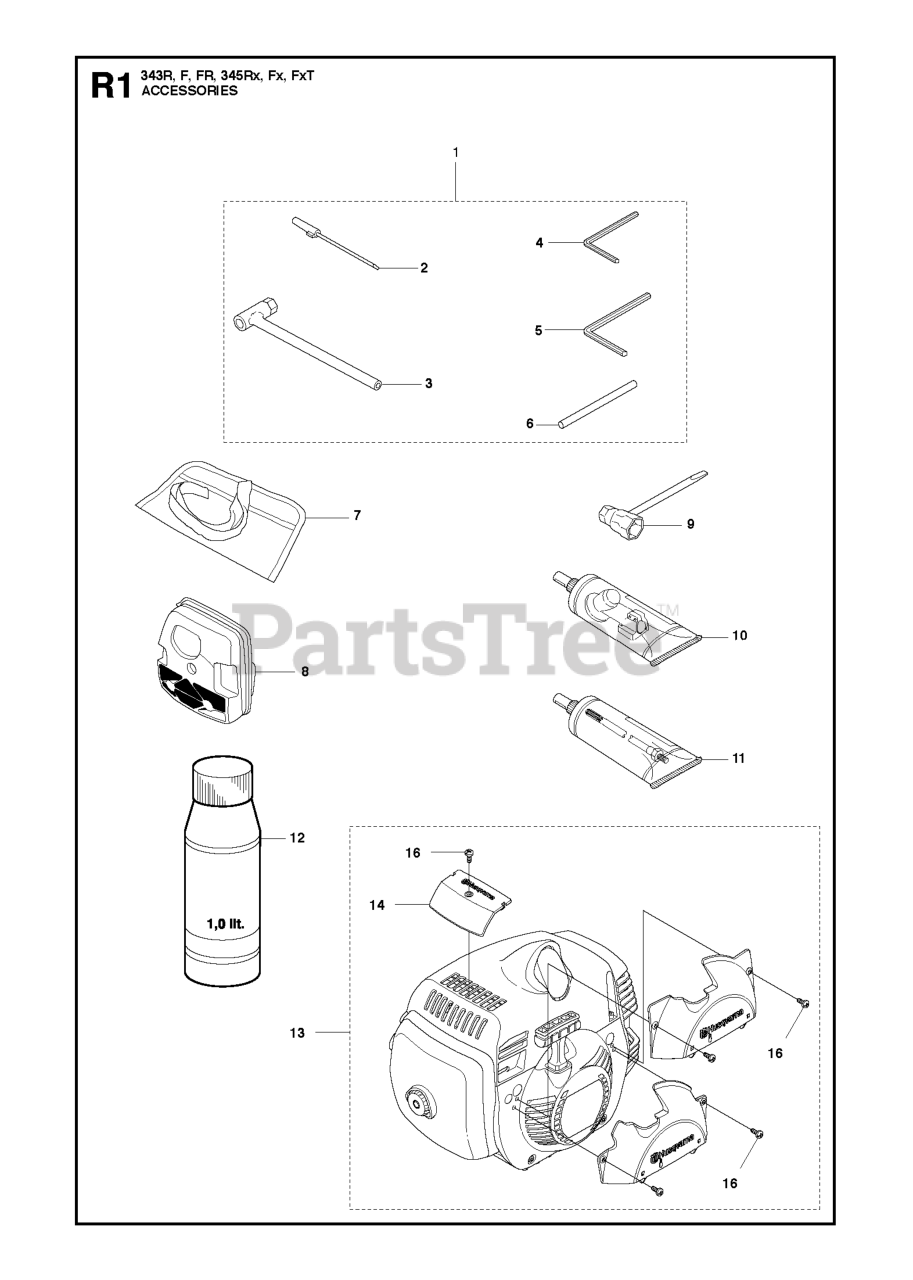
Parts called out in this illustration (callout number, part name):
2	COMBI TOOL
3	L-SPANNER
4	L-SPANNER
5	GREASE
6	Grease Gun
7	WINTER KIT
9	WRENCH
